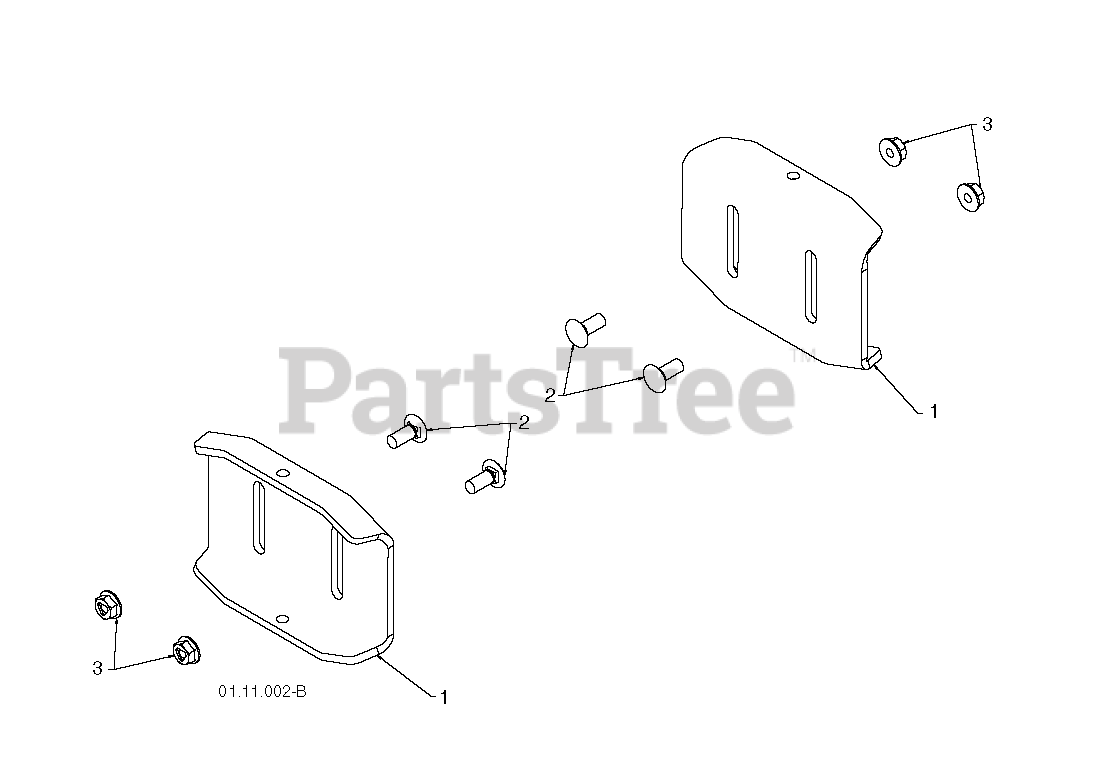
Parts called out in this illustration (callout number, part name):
1	SKID PLATE
2	BOLT
3	NUT.LOCK.5/16-18
